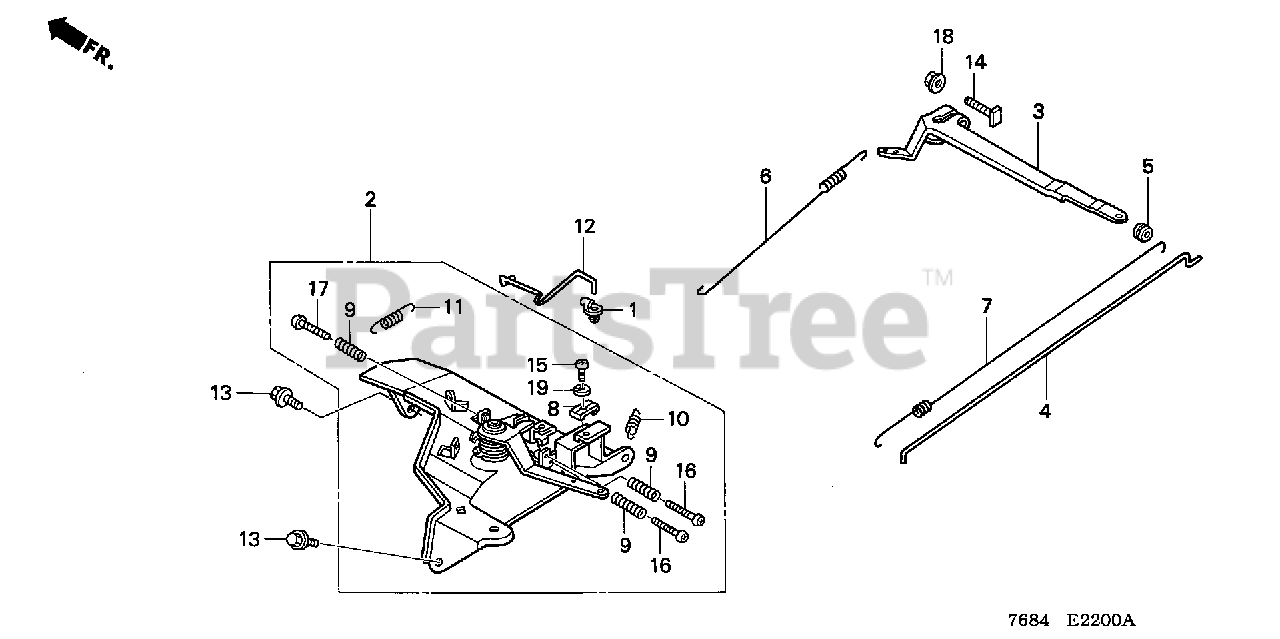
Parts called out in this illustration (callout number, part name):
1	JOINT, ROD
2	CONTROL ASSY.
3	ARM, GOVERNOR
4	ROD, GOVERNOR
5	COLLAR, GOVERNOR ROD
6	SPRING, GOVERNOR (L=145.0MM) (WIRE DIAMETER 1.0MM)
7	SPRING, THROTTLE RETURN
8	HOLDER, CABLE
9	SPRING, CONTROL ADJUSTING
10	SPRING, CABLE RETURN
11	SPRING, CABLE RETURN
12	ROD, CHOKE
13	BOLT, FLANGE (6X12) (CT200)
14	BOLT, GOVERNOR ARM
15	BOLT, RECESSED (5X16)
16	SCREW, PAN (5X25)
17	SCREW, PAN (5X35)
18	NUT, FLANGE (6MM)
19	WASHER, SPRING (5MM)
